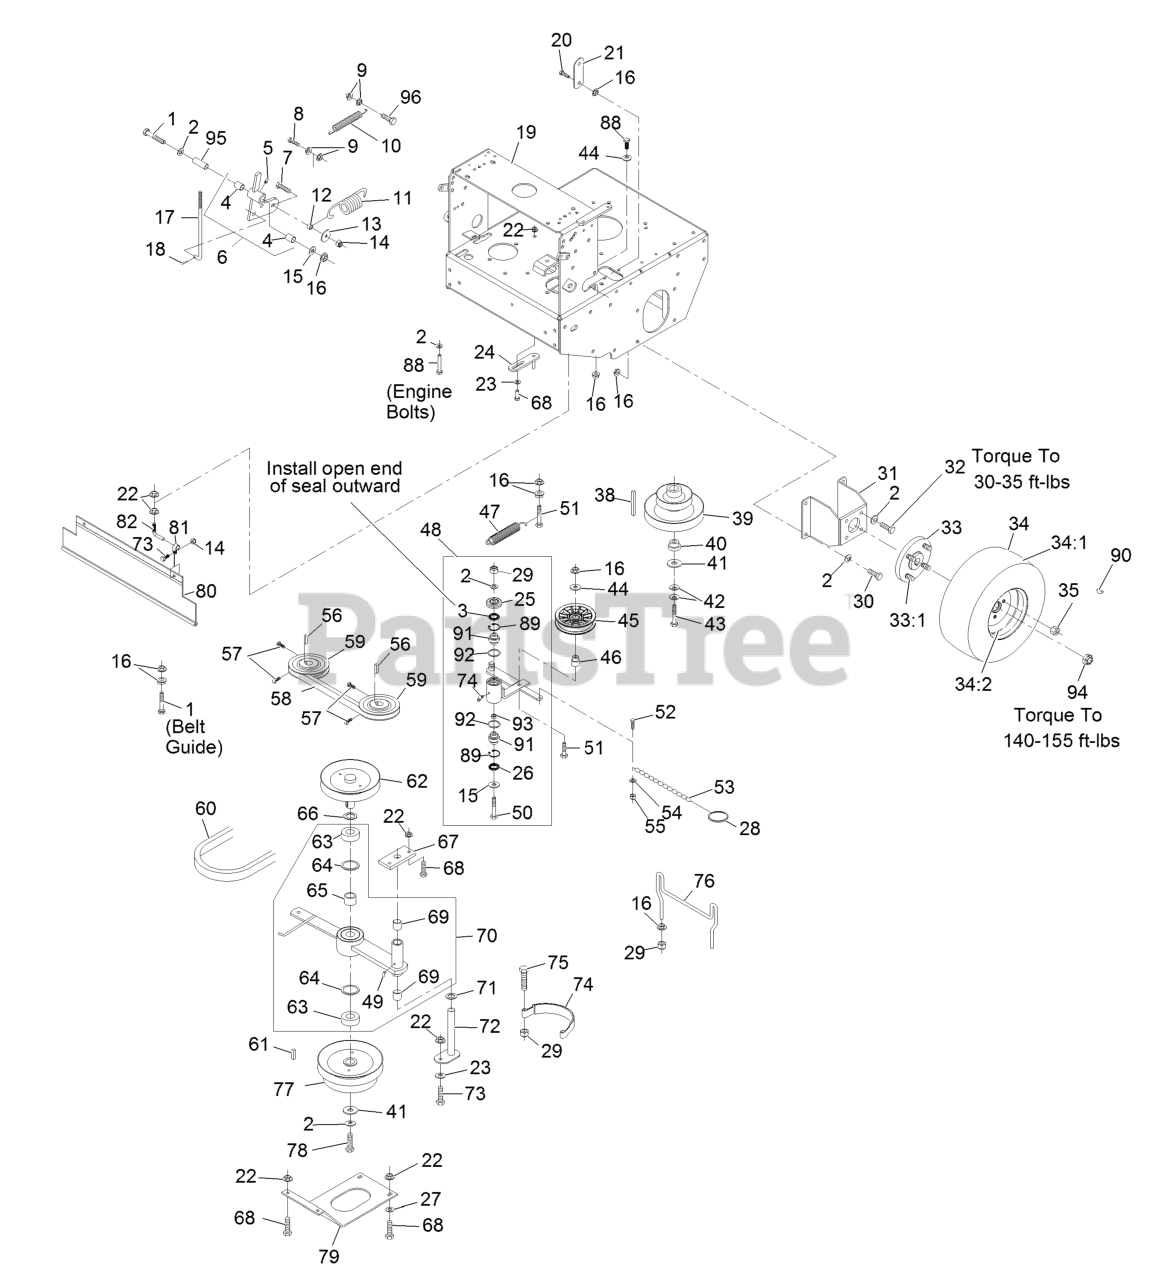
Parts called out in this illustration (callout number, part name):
1	SCREW-HH
2	WASHER-BELLEVILLE
3	SEAL-LIP, SINGLE
4	SLEEVE-BEARING
5	FITTING-GREASE
6	ASM,PIVOT W/BUSHINGS
7	SCREW-HH
8	SCREW-HH
10	SPRING,EXTENSION
11	SPRING,EXTENSION
12	SPACER,CLUTCH ANCHOR
14	NUT-LOCK, NI
15	WASHER-FLAT
16	NUT-HHF, WHIZ
17	LINKAGE,LOWER
18	PIN-COTTER
19	KIT, TTS ENG DECK
20	SCREW-HH
21	ARM-LIFT, DECK
23	WASHER-SPRING
24	GUIDE-BELT
25	GUARD-TOP
26	SEAL-LIP, DOUBLE
27	WASHER-FLAT
28	RING-SPLIT
29	NUT-LOCK, NI
30	SCREW-HH
31	WLD,MOTOR MOUNT 48&52
32	SCREW-HH
33	WHEEL HUB ASM
33:1	STUD-WHEEL
34	WHEEL AND TIRE ASM
34:1	TIRE-TURFMASTER
34:2	RIM-WHEEL
35	NUT-LUG
38	KEY,MACH 1/4X1/4X2-5/8
39	SHEAVE, DRIVE
40	BUSHING,CLUTCH KEEPER
42	WASHER-SPRING
43	SCREW-HH
44	WASHER-FLAT
45	PULLEY-IDLER, FLAT
46	BUSHING-IDLER
48	KIT,PUMP IDLER ARM TTHP
49	FITTING-GREASE
50	SCREW-HH
51	SCREW-HH
52	SCREW-HSH
53	CHAIN-LINK, TWIST
54	WASHER-FLAT
55	NUT-LOCK, NI
57	SCREW-SET, SQH
58	BELT,COG A 50.55
59	SHEAVE ASM
60	BELT,B-38.0
62	SHEAVE, W/ SHAFT
63	BEARING,CLUTCH SHAFT
64	RING-SNAP
65	SPACER,CLUTCH BEARING
66	WASHER-SPACER
67	PLATE-CLUTCH PIVOT
68	SCREW-HH
69	SLEEVE,BEARING
70	ASM,CLUTCH ARM W/BEARING
71	WASHER-SPACER
72	WLD,PIN PIVOT
73	SCREW-HH
74	BAND,BRAKE BLADE
75	SCREW-HH
76	GUIDE,BELT (PLTD)
77	SHEAVE,6.13 W/HUB
78	SCRW,CAP HH
79	PLATE-GUARD
80	SHIELD-DRAG
81	CLIP-LOOM
82	MOUNT,DRAG SHIELD
88	SCREW-HH
89	RING-SNAP
90	KEY-WOODRUFF
91	BEARING-SPHERICAL
94	NUT-LOCK
95	BUSHING
96	SCREW-HH
